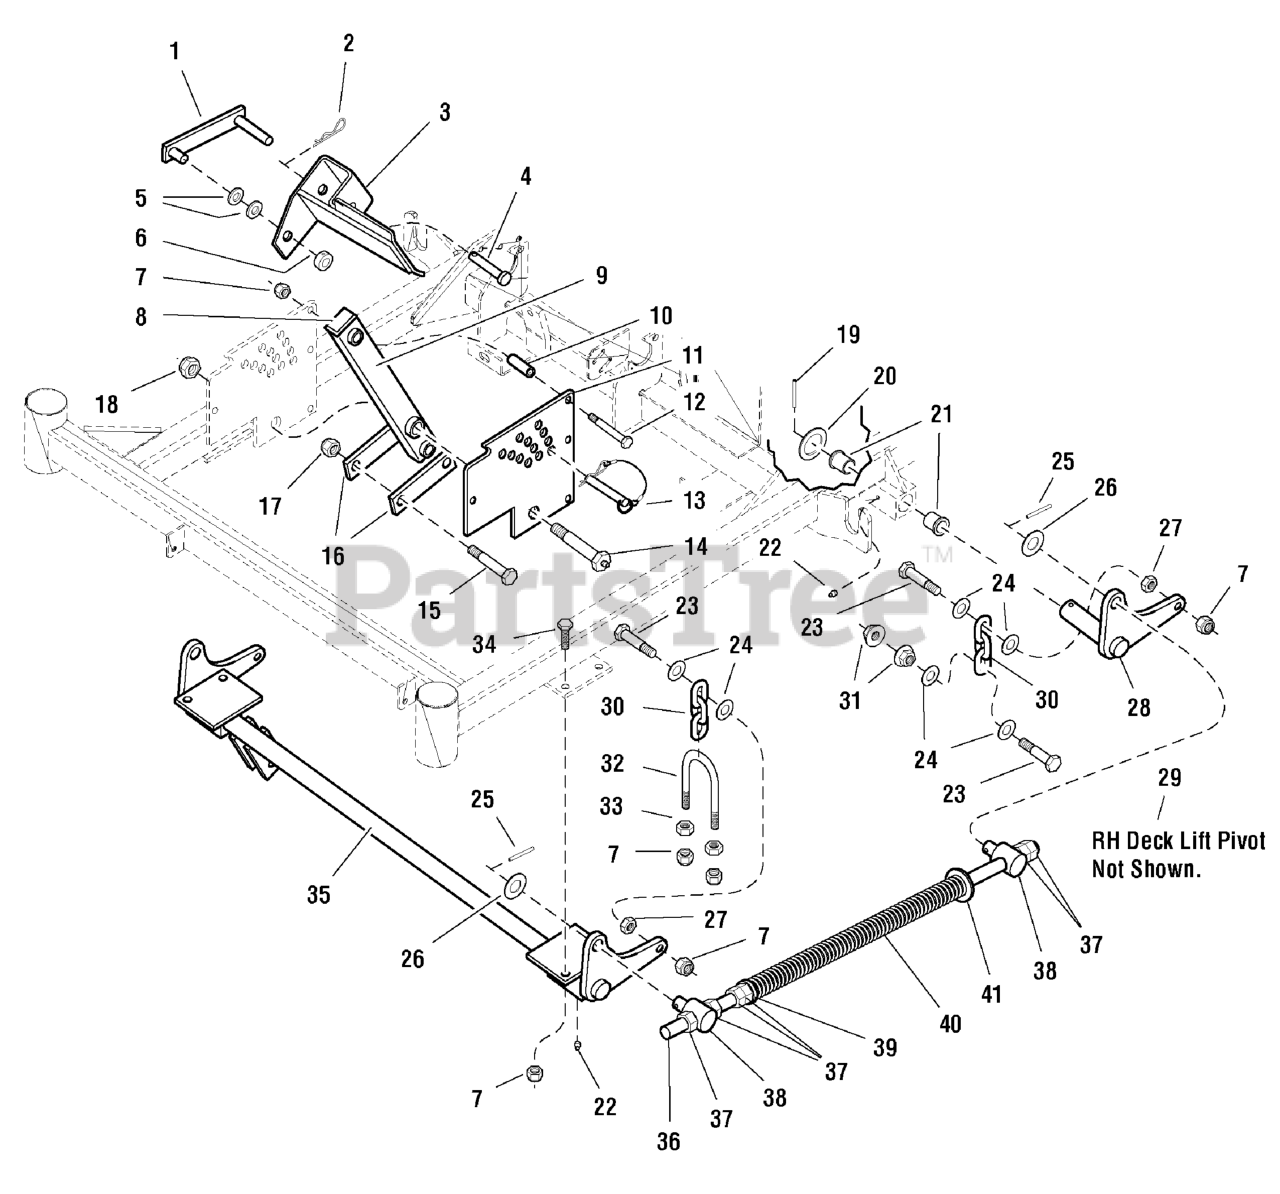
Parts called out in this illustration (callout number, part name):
1	DECK LIFT LOCK
2	HAIRPIN CLIP
3	WELD, DECK LIFT PEDAL
4	PIN, Clevis, 1/2 x 2-1/2
5	WASHER, 1/2 SAE
6	COLLAR, Split, 1/2
7	NUT, 3/8-16 HEX NYLON LOCK
9	ARM, Deck Lift Pivot
10	SPACER, .38 x .50 x 1.56
11	DECK HEIGHT PLATE
12	BOLT, 3/8-16 X 2-3/4" GD5 CZ
13	PIN, 1/2 x 3-1/2 w/ Lanyard
14	LIFT PIVOT BOLT
15	BOLT, 1/2-20 x 3
16	LINK, Deck Lift
17	NUT, Hex, Nylon Lock, 1/2-20
18	NUT, 5/8-11 Hex Jam Nylon Lock
19	PIN, Roll, 3/16 x 1-1/2
21	BUSHING, Flange
22	GREASE FITTING
23	BOLT, 3/8-16 X 1-3/4" GD5 CZ
24	WASHER, 3/8 SAE
25	PIN, Spring, 3/16 x 1-1/4
26	WASHER, 5/8" SAE
27	NUT, 3/8-16 HEX JAM
28	DECK LIFT PIVOT - LH
30	CHAIN, 3 LINKS
31	NUT, 3/8-16 Hex Serrated Flange
33	NUT, 3/8-16 Hex
34	BOLT, 3/8-16 X 1-1/4" GD5 CZ
35	DECK LIFT SHAFT & MOUNT ASSEMBLY
36	SPRING ROD
37	NUT, 5/8-11 Hex
38	SPRING ROD PIVOT
39	SPACER, .63 x 1.06 x .23
40	SPRING, Deck Lift
41	WASHER, 5/8" USS
